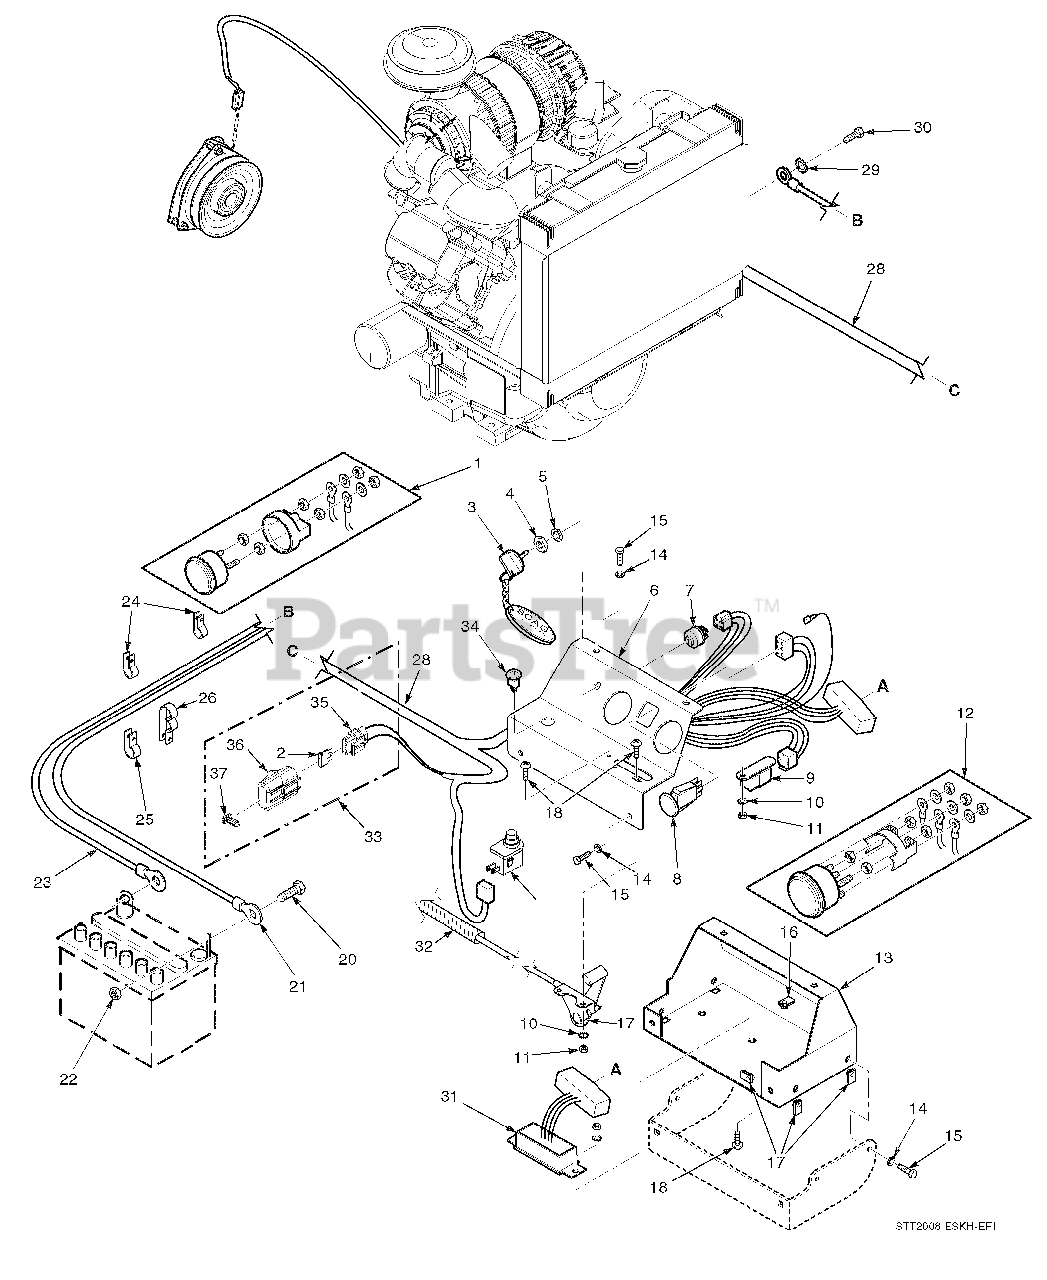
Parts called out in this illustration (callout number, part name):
1	Volt Meter
2	Fuse, 20 AMP
3	Key, Ignition
4	Nut, Hex 5/8-32
5	Lockwasher, 5/8" Internal
6	Instrument Panel, Top w/Decals
7	Key Switch
8	Switch, PTO
9	Relay
10	Lockwasher, #10 External Tooth
11	Nut, Hex #10-32
12	Water Temp. Gauge
13	B ase, Instrument Panel
14	Lockwasher, 1/4"
15	Bolt, Hex Head 1/4-20 x 3/4"
16	U-Nut, 1/4-20
17	Throttle Controls
18	Screw, Phillips Washer Head #10-32 x 1/2"
19	Switch, Interlock-Seat
20	Bolt, Hex Head 1/4-20 x 1/2"
21	Cable, Battery - Red
22	Nut, Hex 1/4-20
23	Cable, Battery - Black
24	Clamp, Cable 1/2" ID.
25	Clamp, Cable 3/4" ID.
26	Clamp, Cable
27	Sending Unit, Water Temp.
28	Wire Harness, STT Liquid Cooled Electronic Fuel Injection
29	Lockwasher, 5/16" External Tooth
30	Bolt, Hex Head M8-1.25 x 20
31	Electronic Module
32	Heatshield, Flexible
33	Single Fuse Assembly, Sealed
34	Indicator Light, Check Engine
35	Fuse Holder
36	Cover, Sealed Single
37	Clip, Wire
